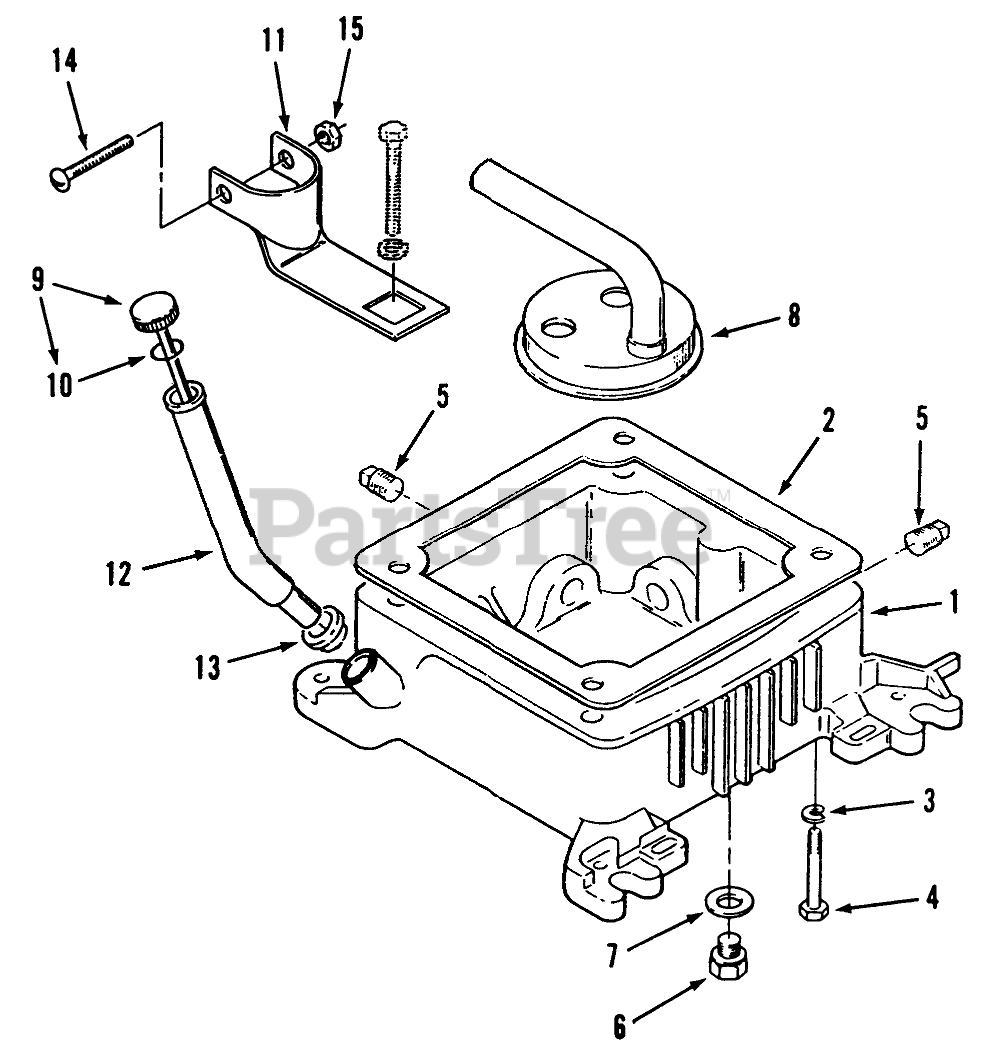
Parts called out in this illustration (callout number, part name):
1	Oil Base (Includes All Plugs and Plug Gasket)
2	Gasket
3	WASHER-FLAT
4	HHCS 3/8-16 X 3 3/4
5	PLUG - SQUARE HEAD
6	Plug
7	Gasket
8	Cup-Oil Pump Intake
9	Oil Fill Cap and Indicator (Includes "O" Ring)
10	O-Ring
11	FILL TUBE BRACKET
12	Oil Fill Tube-Chrome 15-3/4" Lg
13	Seal
14	Screw
15	NUT - SPEED
